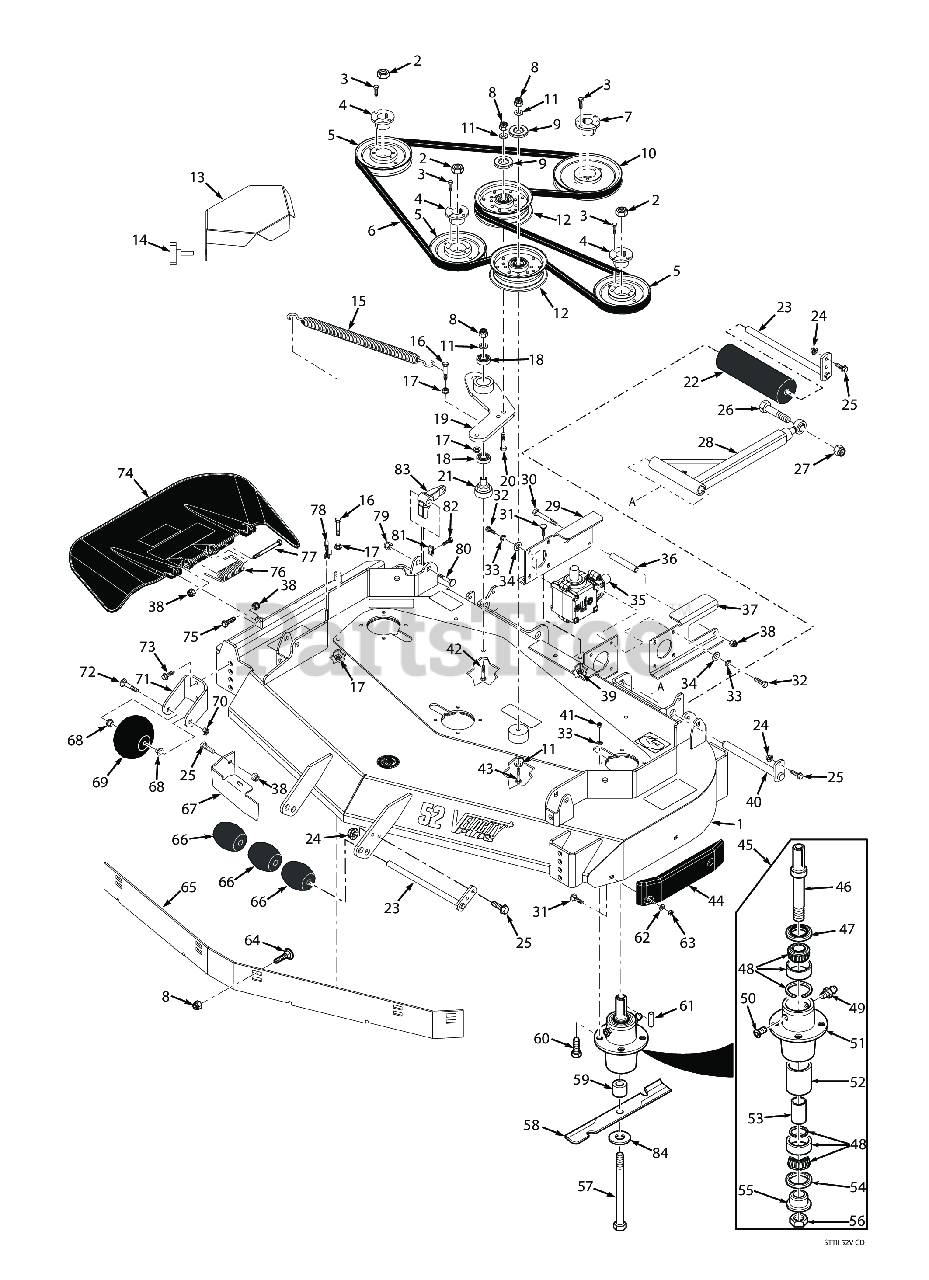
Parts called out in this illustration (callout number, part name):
1	Cutter Deck w/Decals - 52V
2	Hex Locknut, Elastic Stop, 3/8-16
3	Bolt, Hex Head 1/4-20 x 1" Grade 8 Black
4	Hub, Tapered 1-1/8" Bore
5	Pulley, 5.75 O.D. (Gasoline Engines)
6	Belt, Cutter Deck Drive
7	TAPERED HUB, 1.00" BORE
8	HEX NUT, ELASTIC STOP LOCK, 3/8-16
9	Quick Pin, 5/16" Dia.
10	Pulley, 6.95" O.D. - 72"
11	Flatwasher, 3/8 (.391 x .938 x .105 HD) Grade 8
12	Idler Pulley, Belt Clutch
13	Belt Cover
14	Knob, w/stud 3/8-16 x 1-1/4"
15	Spring, Cutter Deck
16	Bolt, Hex Head 3/8-16 x 1-1/2" Grade 8 Black
17	NUT, 3/8-16 SERRATED FLANGE HEX HEAD
18	BEARINGS, BALL, NEUTRAL RETURN
19	Idler Arm, Cutter Deck
20	Capscrew, Hex Head 3/8-16 x 2.75"
21	Pivot, Idler - Short
22	Wheel, Anti-ScalpRelief Fitting, Tapered Spindle
23	Shaft Weldment, Guide Roller
24	Nut, Serrated Flange 5/16-18 (Right Front Engine Mounting, Briggs and Kohler Only)
25	Bolt, Heax Head 5/16-18 x 1" (48V / 52V)
26	BOLT, HEX HEAD 5/8-11 X 4-1/2"
27	HEX LOCKNUT, ELASTIC STOP, 5/8-11
28	Push Arm (Includes 64,60,62)
29	Mounting Plate, RH Gearbox
30	Bolt, 5/16-18 x 4-3/4" Hex Head
31	Bolt, 5/16-18 x .75 RHSN Carriage
32	Bolt, Heax Head 5/16-18 x 1" (48V / 52V)
34	Flatwasher, 5/16-.375 x .875 x .083 (35BV & 37BV-EFI)
35	Gearbox Assembly, Deck Drive
36	Spacer, Gearbox Mount
37	Mounting Plate, LH Gearbox
38	HEX NUT, ELASTIC STOP LOCK, 5/16-18
39	Nut, Serrated Flange 5/16-18 (Right Front Engine Mounting, Briggs and Kohler Only)
40	Shaft Weldment, Pusharm
41	Lock Nut, 5/16-18 Elastic Stop Grade 8
42	Bolt, Hex Head 3/8-16 x 3" - 52"
43	Capscrew, Hex Head 3/8-16 x 3-3/4"
44	Pad, Deck Wear
45	Cutter Spindle Assembly
46	Spindle Shaft, Tapered Brng
47	SEAL, 2.00 O.D. X 1.50 BORE
48	Tapered Bearing Set (Two Bearings W/Race)
49	GREASE FITTING, STR. 1/4-28 SELF TAP.
50	RELIEF FITTING, TAPERED BEARING SPINDLE
51	Housing, Spindle
52	Spacer, Outside, Cutter Spindle
53	SLEEVE, CUTTER SPINDLE
54	Seal, 2.00" O.D. x 1.625" Bore
55	SPINDLE BUSHING, BOTTOM
56	Nut , Spec ial 1 -1/ 1 6 - 1 8
57	BOLT, HEX HEAD, 5/8-11 X 9-1/2 GR.5
58	Cutter Blade, 18" (52V)
59	Spacer, Spindle Bottom
60	Bolt, Hex Head 5/16-18 x 1-3/4" Grade 8
61	Key, 1/4 x 1/4 x 2.0"
62	Flatwasher, 5/16-.344 x .688 x .065 (48V / 52V)
63	Nut, Center Lock, 5/16-18(32)
64	Carriage Bolt, 3/8-16 x 1.0"
65	Baffle Custom-Cut, 52V (7-Position)
66	Wheel, Anti-Scalp
67	Turbo Baffle - 48V / 52V
68	Bushing, .376" I.D. Oilite
69	Bolt, Carriage 3/8-16 x 4"
70	Bolt, Hex Head 3/8-16 x 1" Ser. Flg.
71	Bracket, Anti-Scalp Wheel
72	Bolt, Hex Head 3/8-16 x 3-1/2"
73	Capscrew, 3/8-16 x 1.0" Serrated Flange Hex Hd
74	Discharge Chute Assembly - 52V
74	Discharge Chute Assy. (CA)
75	Bolt, Hex Head 5/16-18 x 1-1/2" - Front
76	Spring, Discharge Chute
77	Bolt, 5/16-18 x 4-3/4" Hex Head
78	U-Nut, 3/8-16
79	HEX LOCKNUT, ELASTIC STOP, 7/16-14
80	Bolt, Carriage 7/16-14 x 2-1/4"
81	U-Nut, 3/8-16 (short)
82	Bolt, Hex Head 3/8-16 x 2" Special Lock
83	Lever, Deck Level
84	Flatwasher, 5/8-.688 x 1-3/4 x .134 HD
